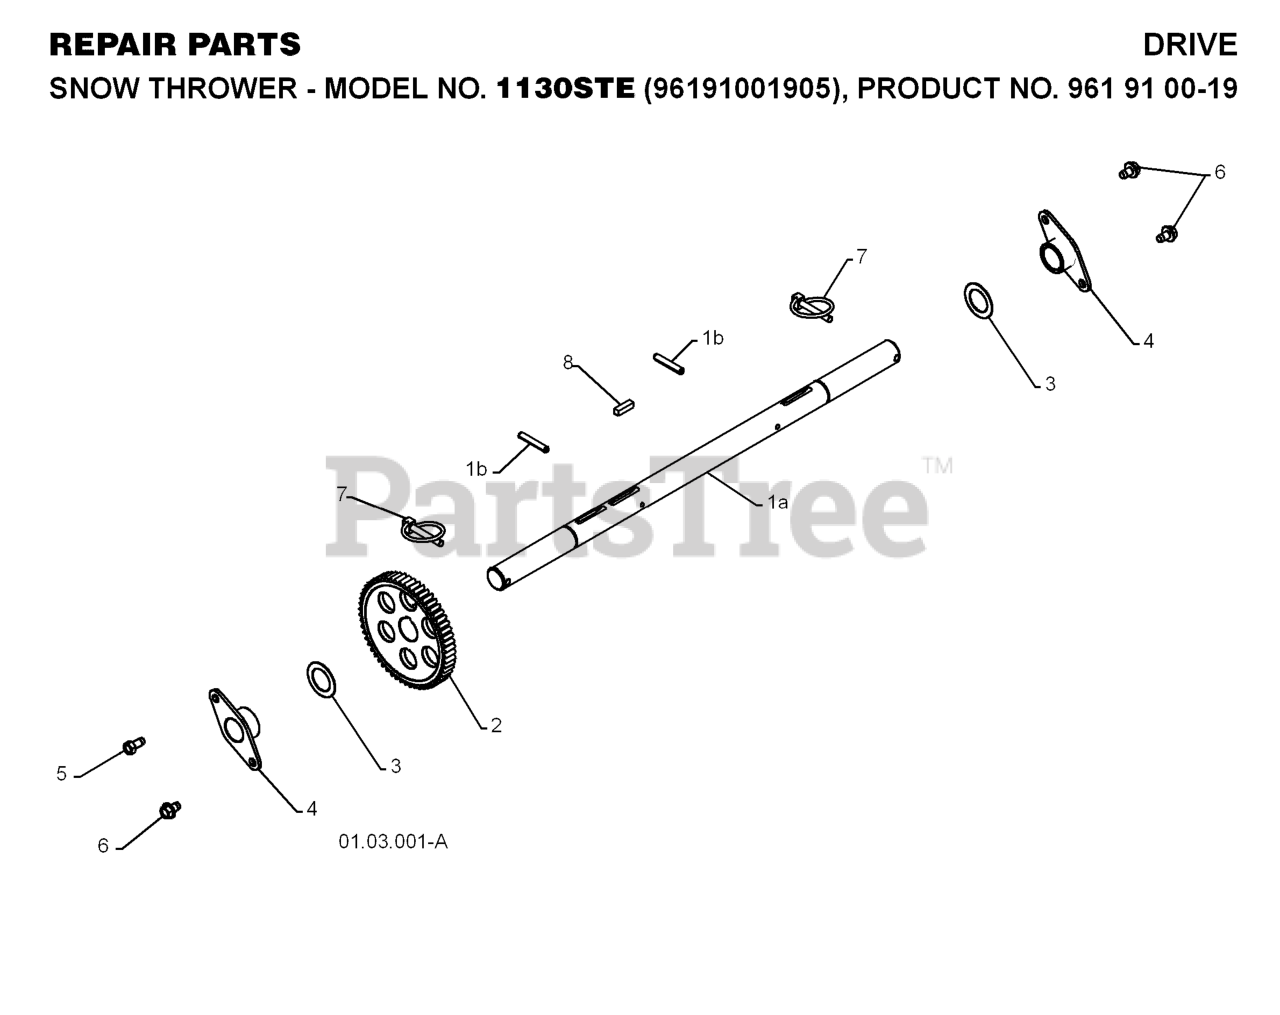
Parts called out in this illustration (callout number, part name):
1	AXLE.ASM.SHAFT.W/ROLLPIN.PS
1A	SHAFT.AXLE.POWER.STEERING
1B	PIN.ROLL.3/16
2	GEAR, AXLE (58T)
3	WASHER TRUST 1"
4	BEARING, AXLE
6	Screw 5/16-18 x 1/2 Hex, Self Tapping 5/16-18 x 1/2
7	PIN KLIK, 1/4
8	KEY, SQUARE 1/4 X .875
